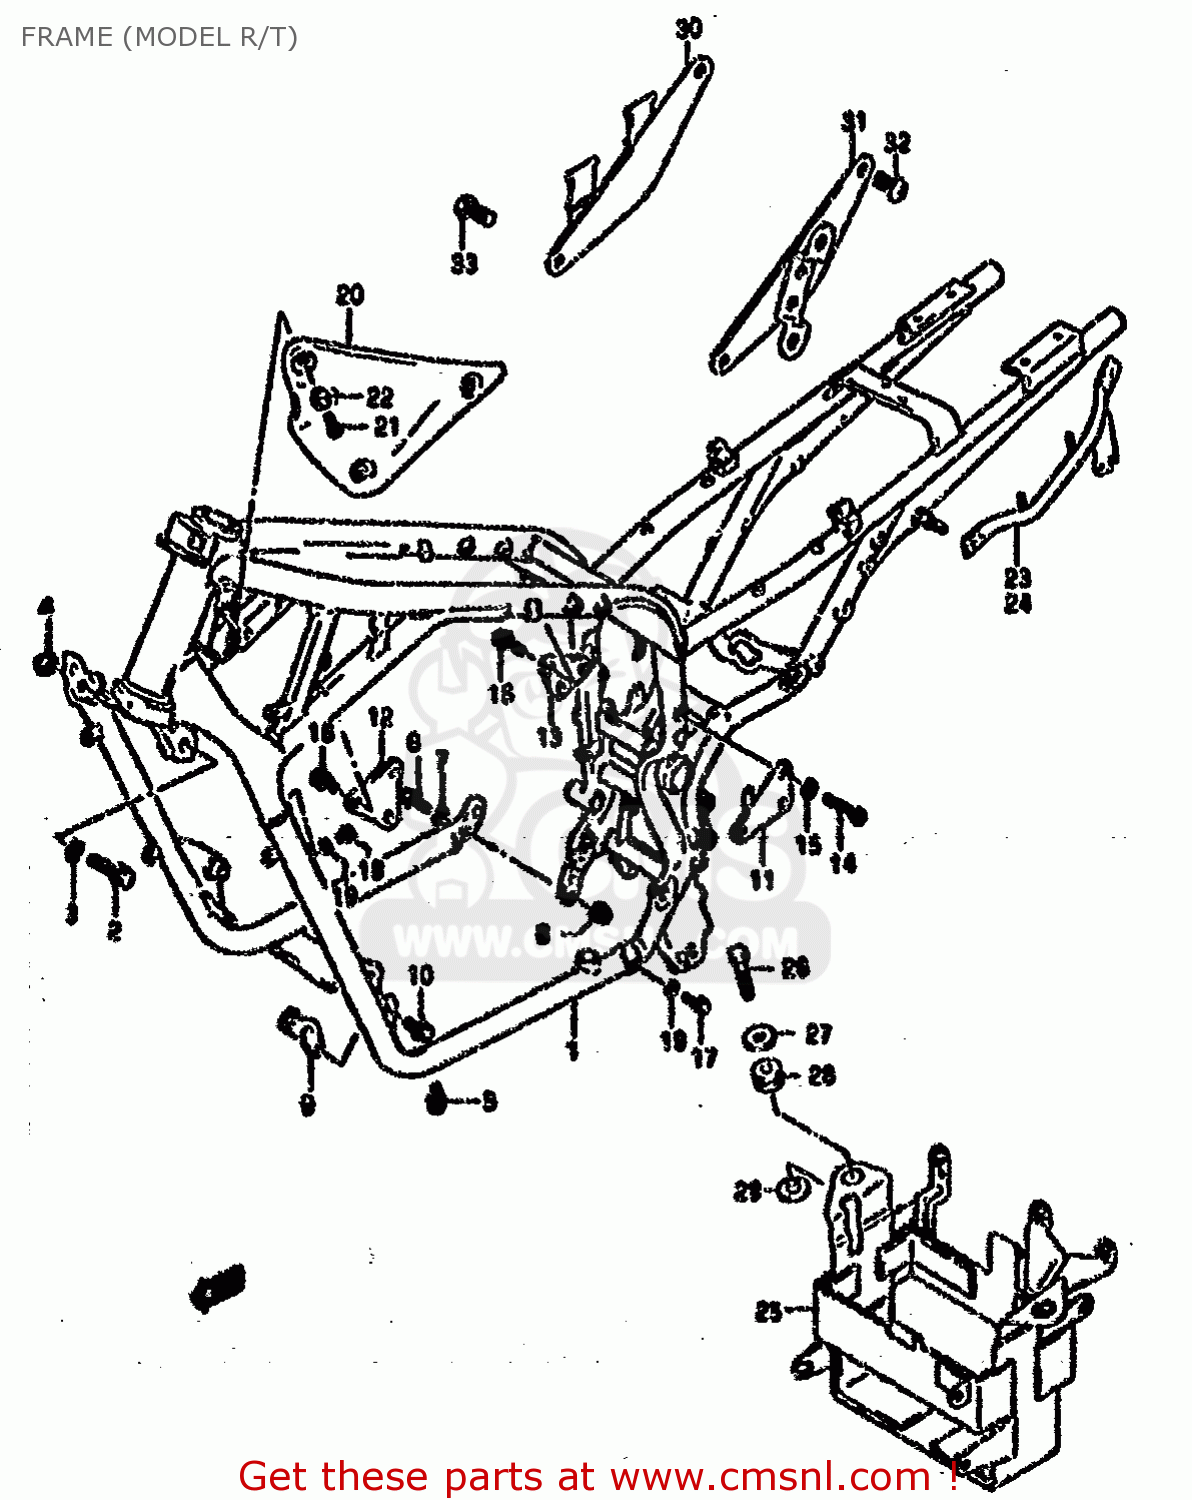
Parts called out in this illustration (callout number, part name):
1	FRAME SET (BLACK)
2	BOLT(10X32)
3	WASHER
4	NUT
5	BOLT
6	BOLT(10X33)
7	WASHER
8	NUT 10MM
9	PLATE,ENGINE MOUNTING NO
10	BOLT
11	PLATE,ENGINE MOUNTING NO
12	PLATE,ENGINE MOUNTING NO
13	PLATE,ENGINE MOUNTING NO
14	BOLT
15	WASHER
16	BOLT
17	BOLT
18	UNION
19	GASKET(6.2X11X1).2 (NAS)
20	COVER,FRAME HEAD,LEFT
21	SCREW(5X14)
22	WASHER(5.2X14X1.5)
23	GRIP,REAR,R.
24	GRIP,REAR LH
25	GRIP,REAR LH
26	BOLT
27	BOLT
28	CUSHION
29	WASHER(6.5X22X1.6)
30	CUSHION
31	PLATE,BATTERY HOLDER
32	SCREW 6X12
33	SCREW
34	SCREW 6X12
35	SCREW
